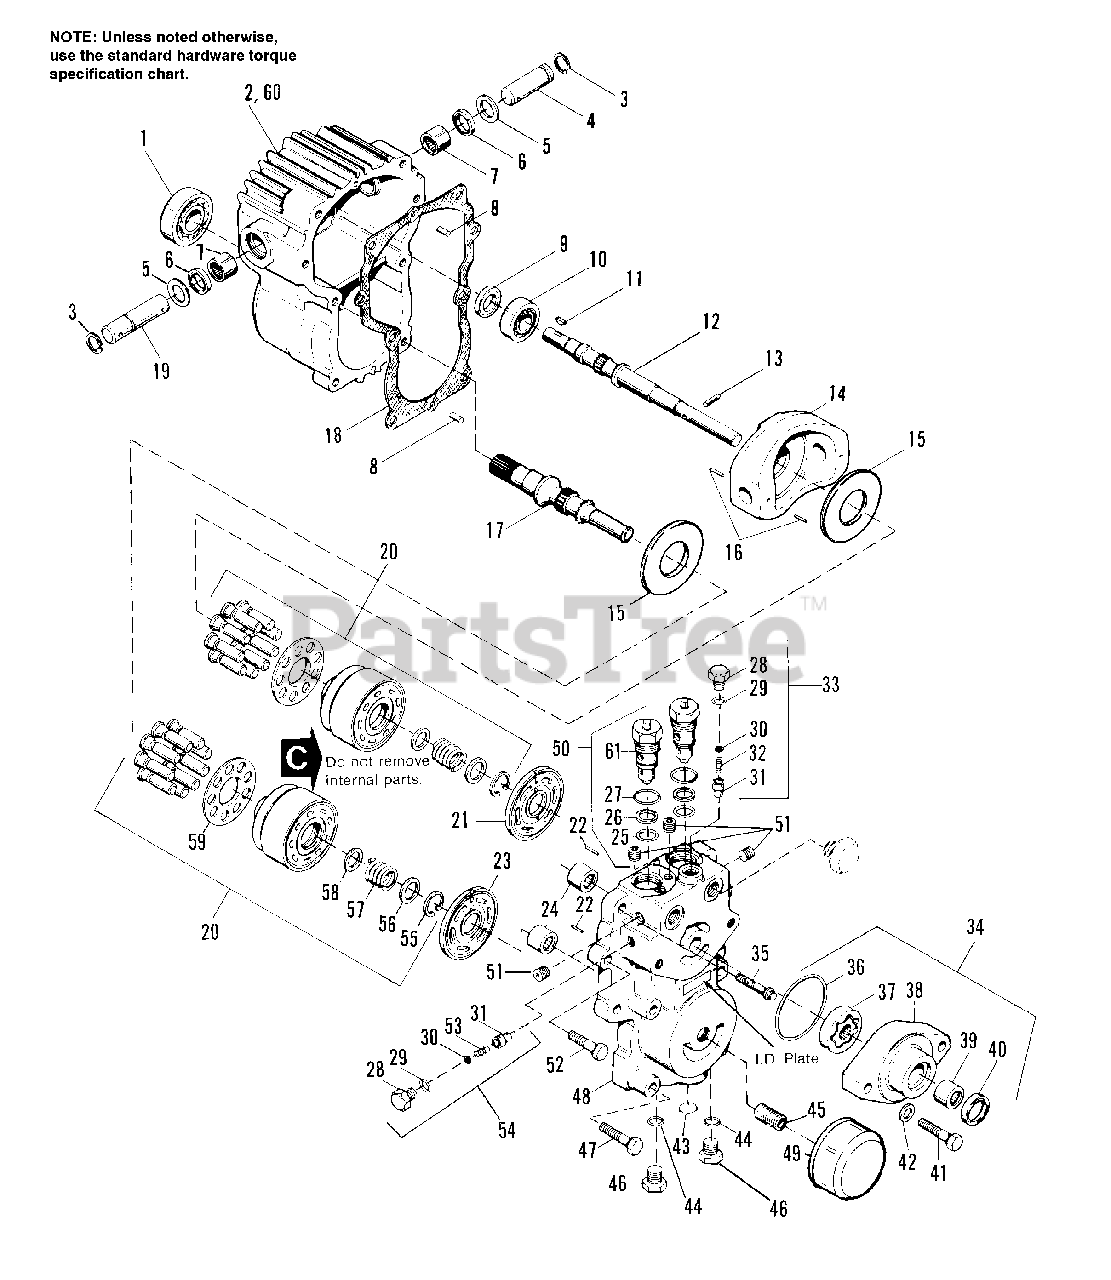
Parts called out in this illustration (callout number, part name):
1	BEARING, Ball
3	RING, Retainer
5	WASHER
7	BEARING, Needle
8	PIN, Headless, Straight
10	BEARING, Ball
11	KEY, Woodruff
12	SHAFT, Pump
13	PIN, Headless
14	PLATE, Swash
15	PLATE, Thrust
16	PIN, Spring, Coiled
17	SHAFT, Motor
20	CYLINDER BLOCK KIT
21	PLATE, Valve, Pump
22	PIN, Straight
23	PLATE, Valve, Motor
24	BEARING, Needle
26	RING, Backup
28	PLUG, Hex Hd.
30	SHIM
31	CONE, Relief Valve
32	SPRING, Relief Valve
33	RELIEF VALVE KIT
34	CHARGE PUMP KIT
35	CAPSCREW, 12 pt.
39	BEARING, Needle
41	CAPSCREW, Hex Hd, 7/16-14 x 2
42	WASHER
45	UNION, Filter
46	PLUG, Hex Hd.
47	CAPSCREW, Hex Hd, 3/8-16 x 2
48	SECTION, Center
49	FILTER, 25 Micron
50	CHECK VALVE & O-RING ASSEMBLY
51	PLUG, Pipe
52	CAPSCREW, Hex Hd, 3/8-16 x 1-1/4
53	SPRING, Relief
54	RELIEF VALVE KIT
55	RING, Retaining
56	WASHER,Rear
58	WASHER, Front
59	RETAINER, Hub
60	HOUSING ASSEMBLY
61	CHECK VALVE
